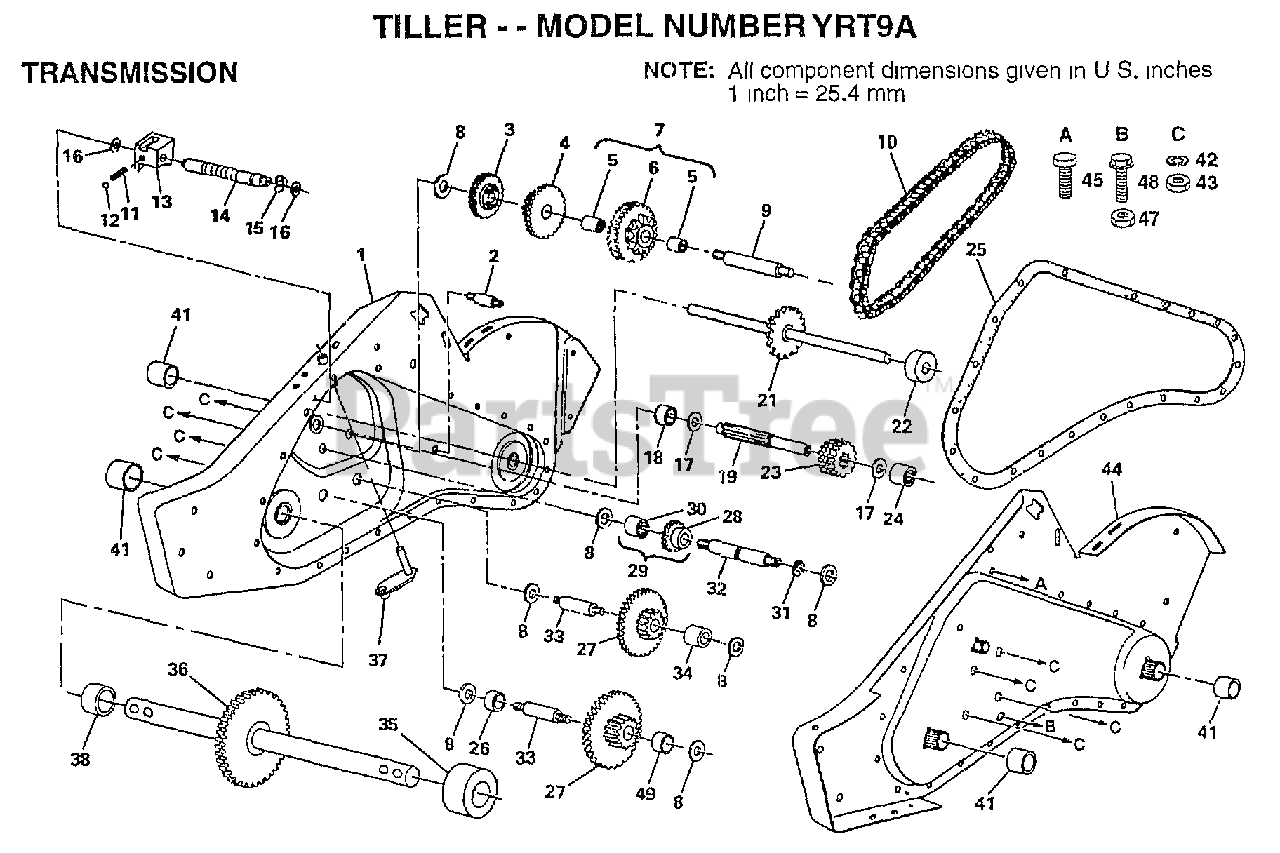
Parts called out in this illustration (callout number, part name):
2	BOLT TI
3	REVERSE GEAR TI
4	CLUSTER GEAR TI
5	"CRT, BEARING"
7	SPROCKET ASSY TI
8	WASHER
9	REDUCTION SHFT TI
10	CHAIN TI
11	SPRING-SHIFT CRT
13	SHIFT FORK TI
14	SHIFT SHAFT TI
15	KLIP RING
16	WASHER SEAL
17	"T, BEARING"
18	"TI, BEARING"
19	SHAFT INPUT
21	SHAFT TINE CRT
22	SPACER CRT
23	INPUT PINION TI
24	NEEDLE BRNG LT
25	GEARCASE GSKT TI
26	SPACER CRT
27	GEAR CLUSTER CRT
28	REVERSE GEAR TI
29	GEAR ASSY TI
30	NEEDLE BEARING TI
31	KLIP RING
32	REVERSE SHAFT TI
33	SHAFT CRT
34	SPACER CRT
35	SPACER CRT
36	SHAFT ASSY CRT
37	BRACKET ASM SHIFT
38	SPACER CRT
41	SEAL ASM-OIL
42	LOCKWASHER
43	NUT.ASF.HEX.7/16
45	SCREW 5/16-18X5/8
47	NUT.HEX.5/16-18
48	BOLT TI
49	SPACER CRT
